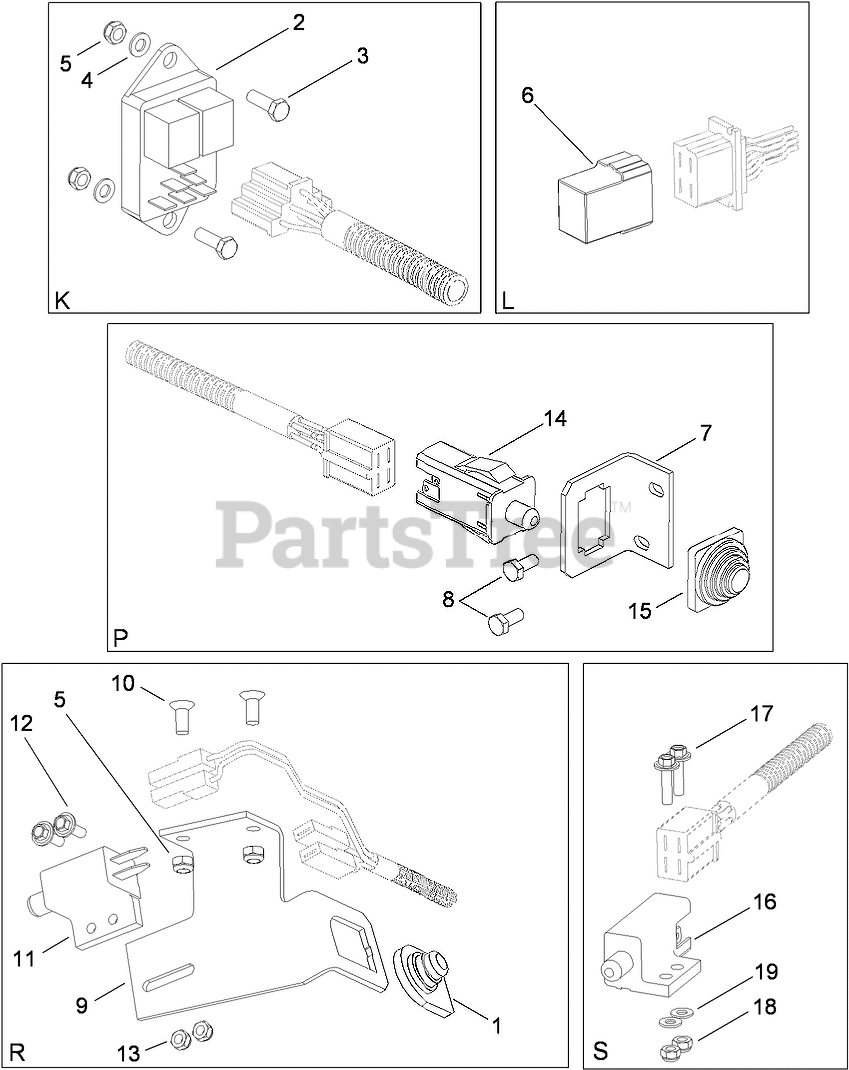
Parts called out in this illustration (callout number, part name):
1	COVER-PROTECTIVE
2	MODULE-CLUTCH
3	SCREW-HH
4	WASHER
5	NUT-LOCK
6	CIRCUIT-MEMORY
7	Holder-Switch
9	HOLDER-SWITCH
11	SWITCH-POLE, SINGLE
13	NUT-HEX
14	Switch-Delta
15	Cover-Switch
16	Switch-Delta
18	NUT-LOCK
19	WASHER
